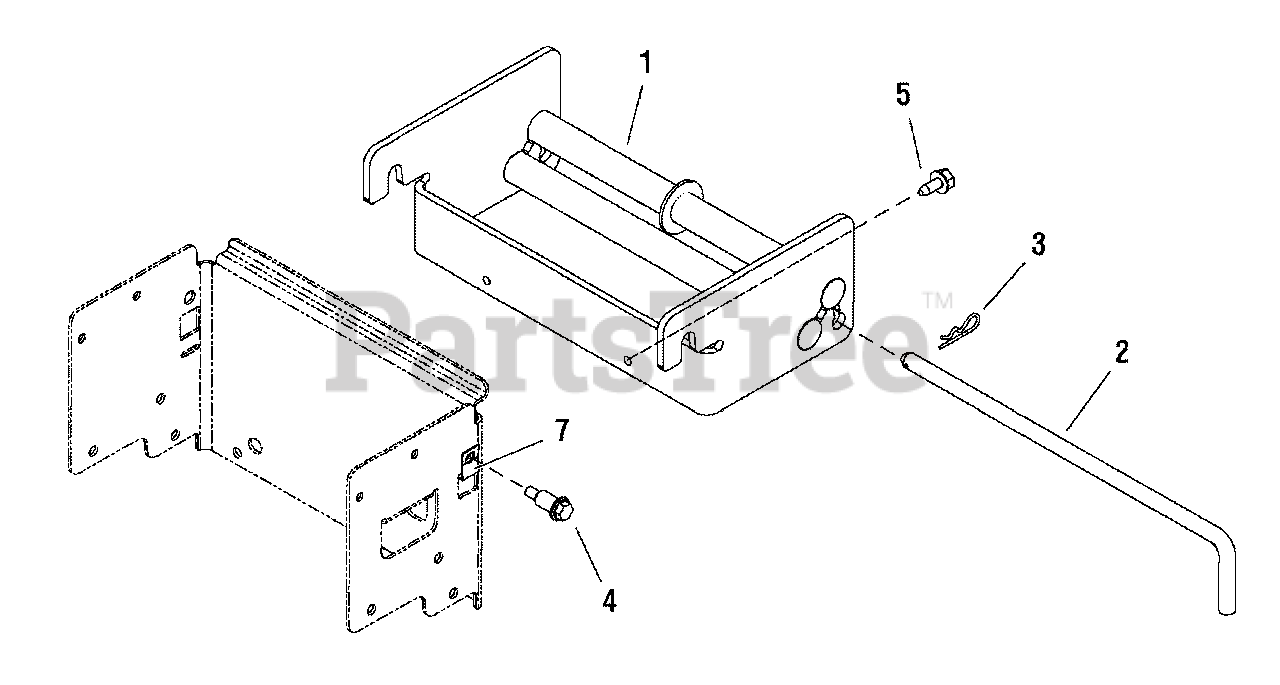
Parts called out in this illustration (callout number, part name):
1	SUPPORT ASSEMBLY, Weight Carrier
2	ROD, Latch
3	CLIP, Hair Pin
4	BOLT, Shoulder 5/16-18 G5
5	SCREW, Hex Washer Head Taptite, 5/16-18 x 3/4
7	NUT, Speed 5/16-18 Lug Type
